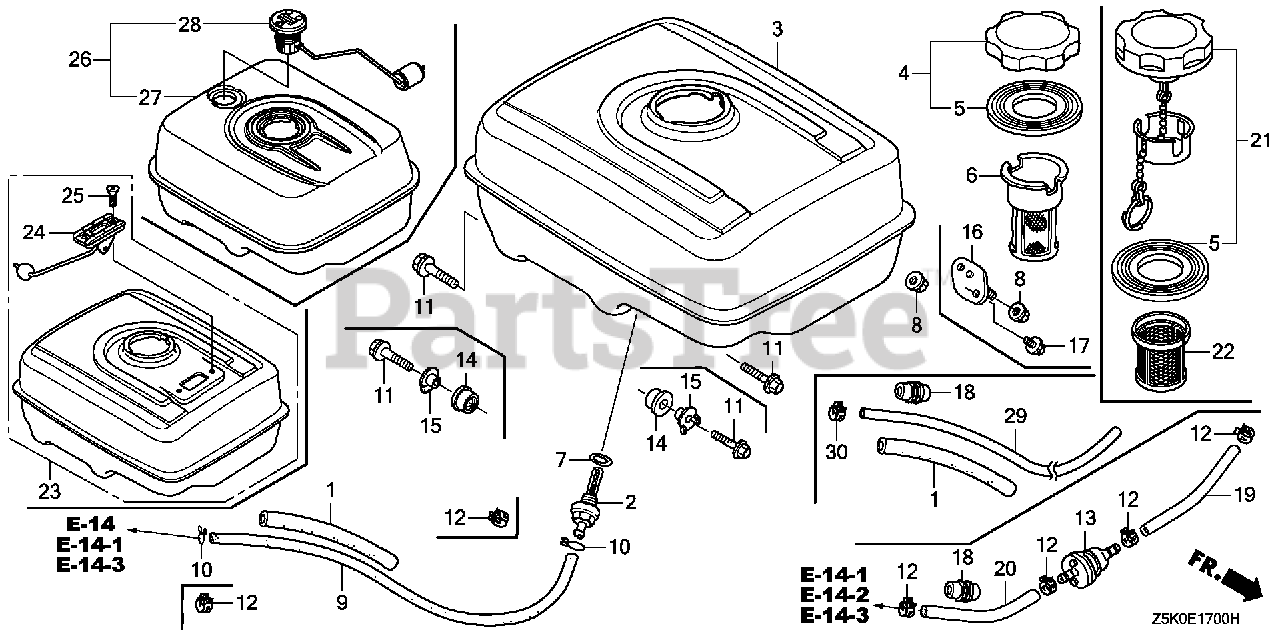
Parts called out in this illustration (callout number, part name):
12	CLIP, TUBE (D8)
13	FILTER, FUEL
18	RUBBER, FUEL (9X15X20)
19	TUBE, FUEL (4.5X150) (FKM)
20	TUBE, FUEL (4.5X120) (FKM)
